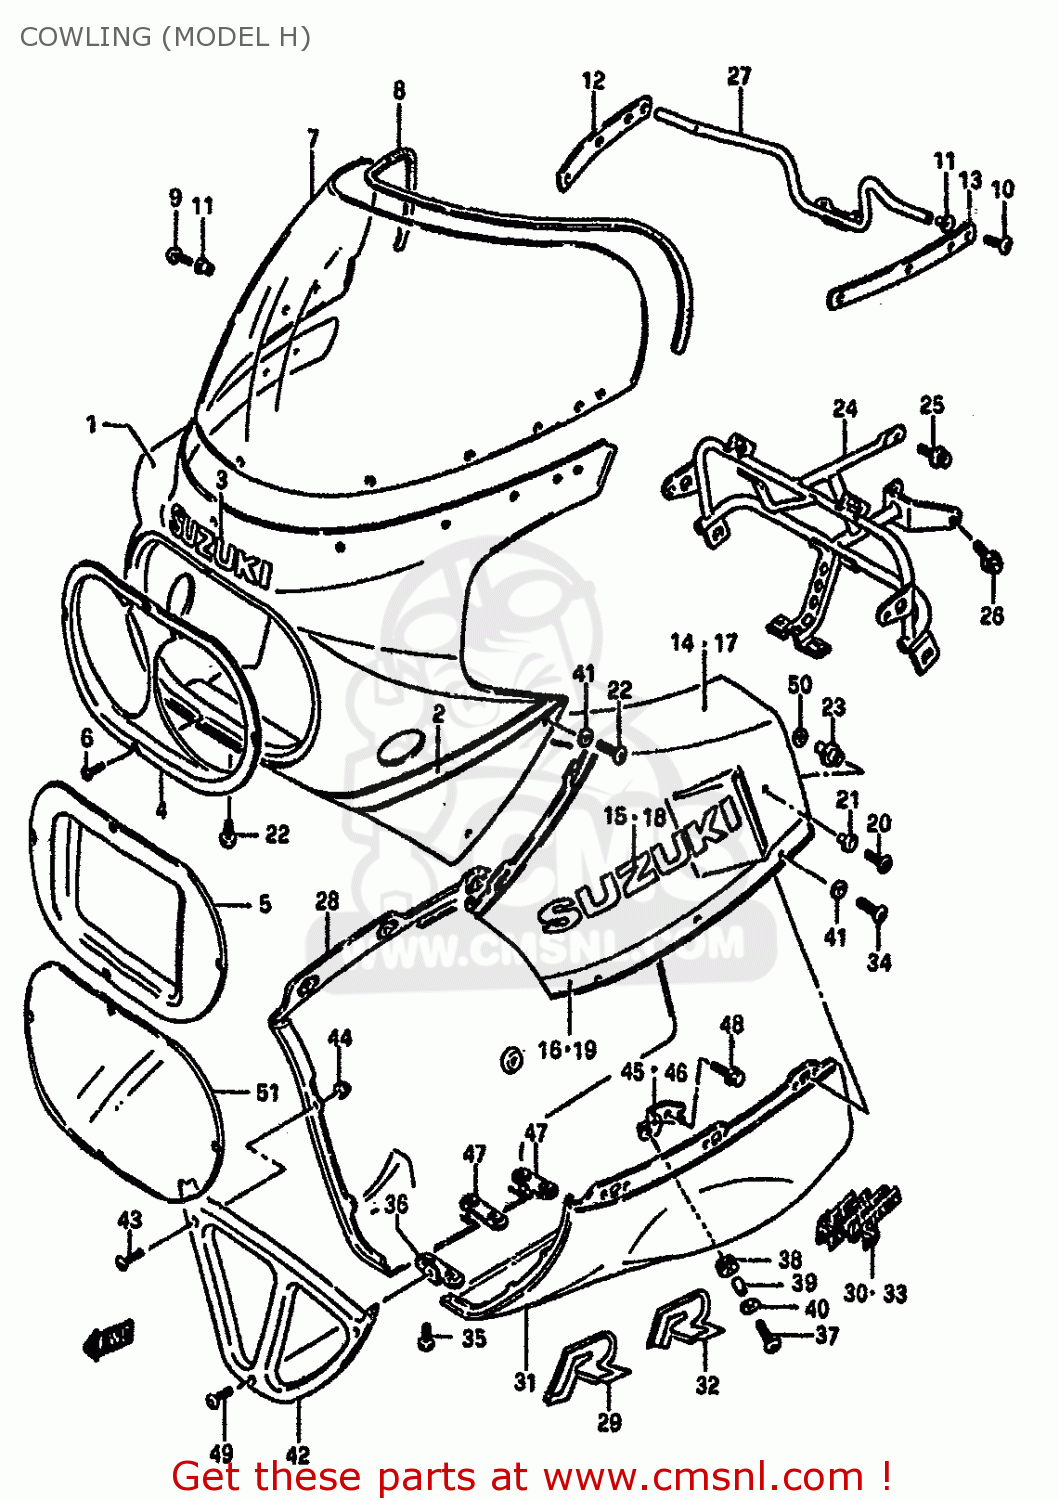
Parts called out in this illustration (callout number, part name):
1	COWLING SET
2	TAPE SET,COWLING BODY
3	EMBLEM
4	COVER,COWLING,FRONT
5	COVER,FRONT (RED)
6	SCREW
7	WINDSCREEN
8	MOLDING
9	SCREW(5X14)
10	SCREW(5X18)
11	NUT,COWLING SCREEN
12	PLATE,RR VIEW MIRROR,R
13	PLATE,RR VIEW MIRROR,L
14	COVER ASSEMBLY,COWLING
15	EMBLEM
16	TAPE SET,COVER SIDE,RIGHT
17	COVER,COWLING SIDE,LEFT
18	EMBLEM
19	TAPE SET,COVER SIDE,LEFT
20	SCREW(6X12)
21	WASHER
22	SCREW(6X16)
23	CUSHION,COWLING
24	BRACE,COWLING
25	BOLT
26	BOLT
27	BRACE,COWLING BODY RR
28	COVER,COWLING,LOWER,RIGHT
29	EMBLEM
30	EMBLEM
31	COVER,COWLING,LOWER,LEFT
32	EMBLEM
33	EMBLEM
34	SCREW(6X16)
35	SCREW(6X16)
36	BRACE,COWLING LWR COVER
37	SCREW(6X20)
38	CUSHION
39	SPACER
40	WASHER(6.5X18X1)
41	WASHER
42	COVER,COWLING,LOWER,FRONT
43	SCREW(5X14)
44	NUT
45	BRACE,COWLING LWR,R
46	BRACE,COWLING LWR,L
47	BRACE,COWLING LWR COVER RR
48	BOLT
49	SCREW(6X16)
50	WASHER
51	COVER,HEADLAMP
